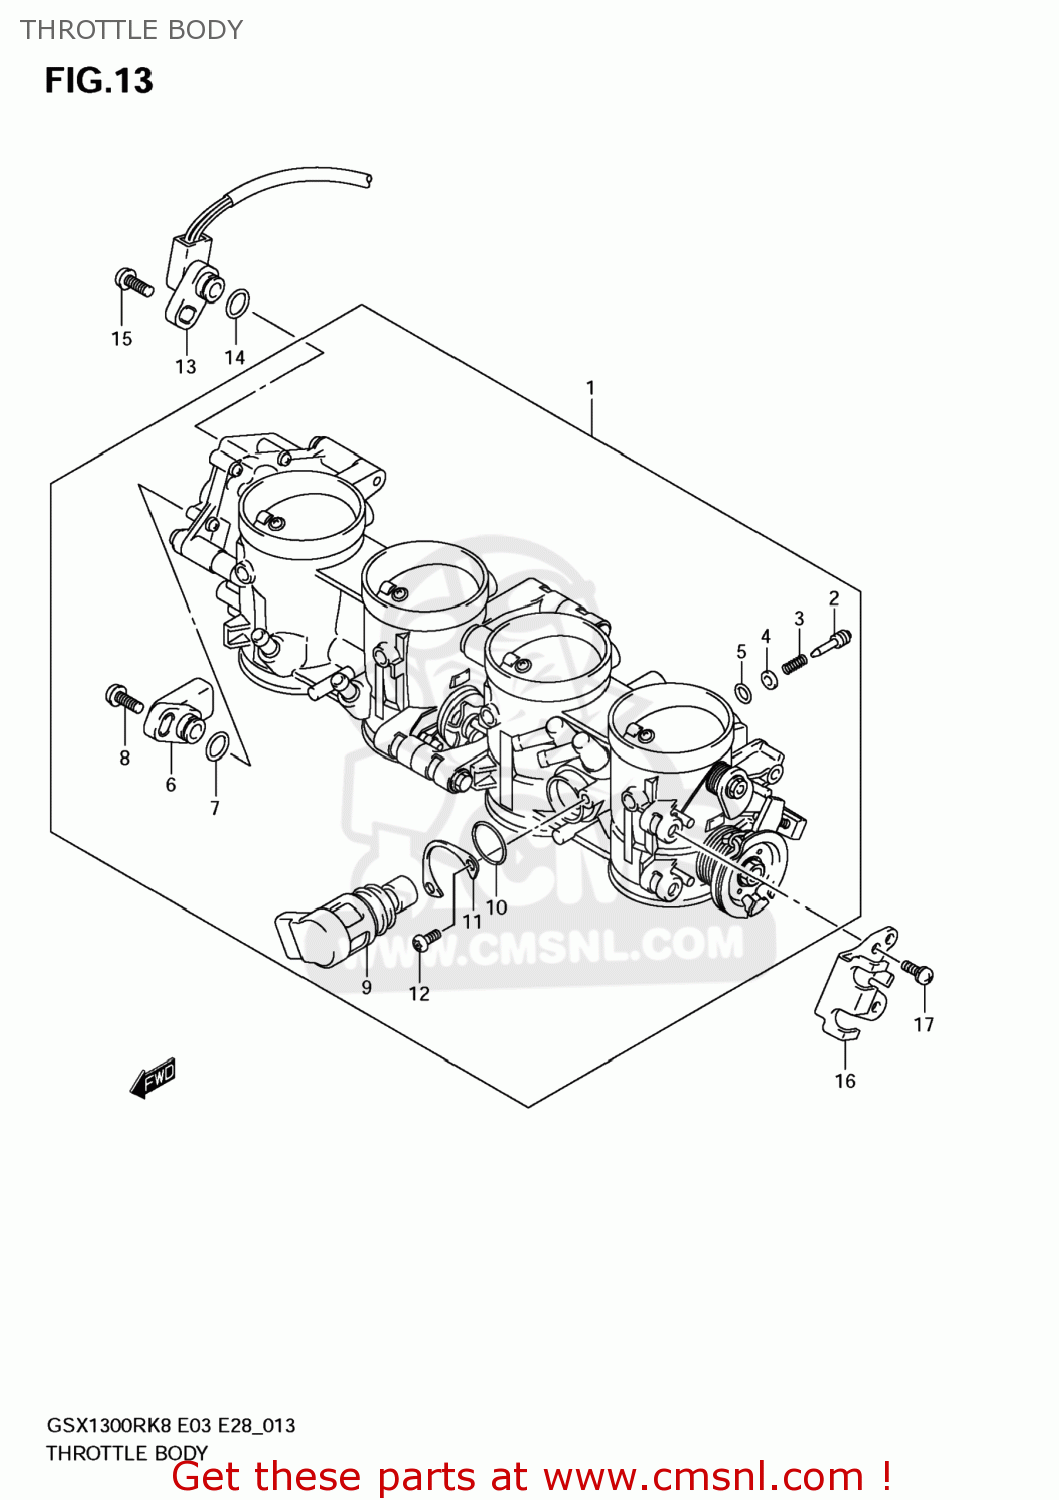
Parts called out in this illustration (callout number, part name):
1	BODY ASSY,THROTTLE
2	SCREW,AIR ADJUST
3	SPRING
4	WASHER
5	O RING
6	SENSOR ASSY,THROTTLE MAIN
7	O RING
8	SCREW
9	VALVE ASSY,ISC
10	O RING
11	PLATE,ISC VALVE
12	SCREW
13	SENSOR ASSY,TH
14	O RING
15	SCREW
16	PLATE,STAY
17	SCREW
